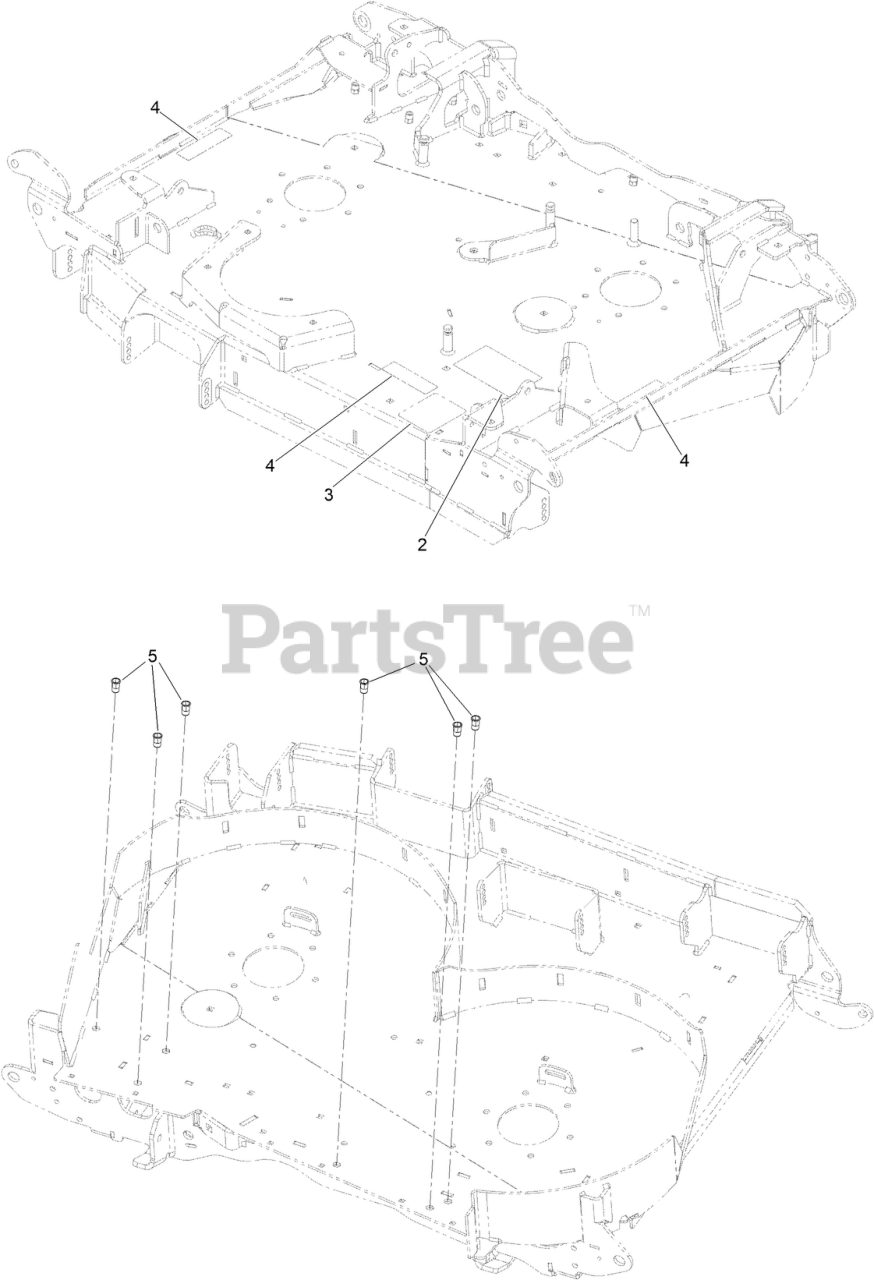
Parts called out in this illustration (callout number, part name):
2	DECAL-DECK BELT ROUTING
3	DECAL-ROLLER, ANTI-SCALP
4	DECAL-COVER, MISSING
5	NUT-CLINCH,HEX
